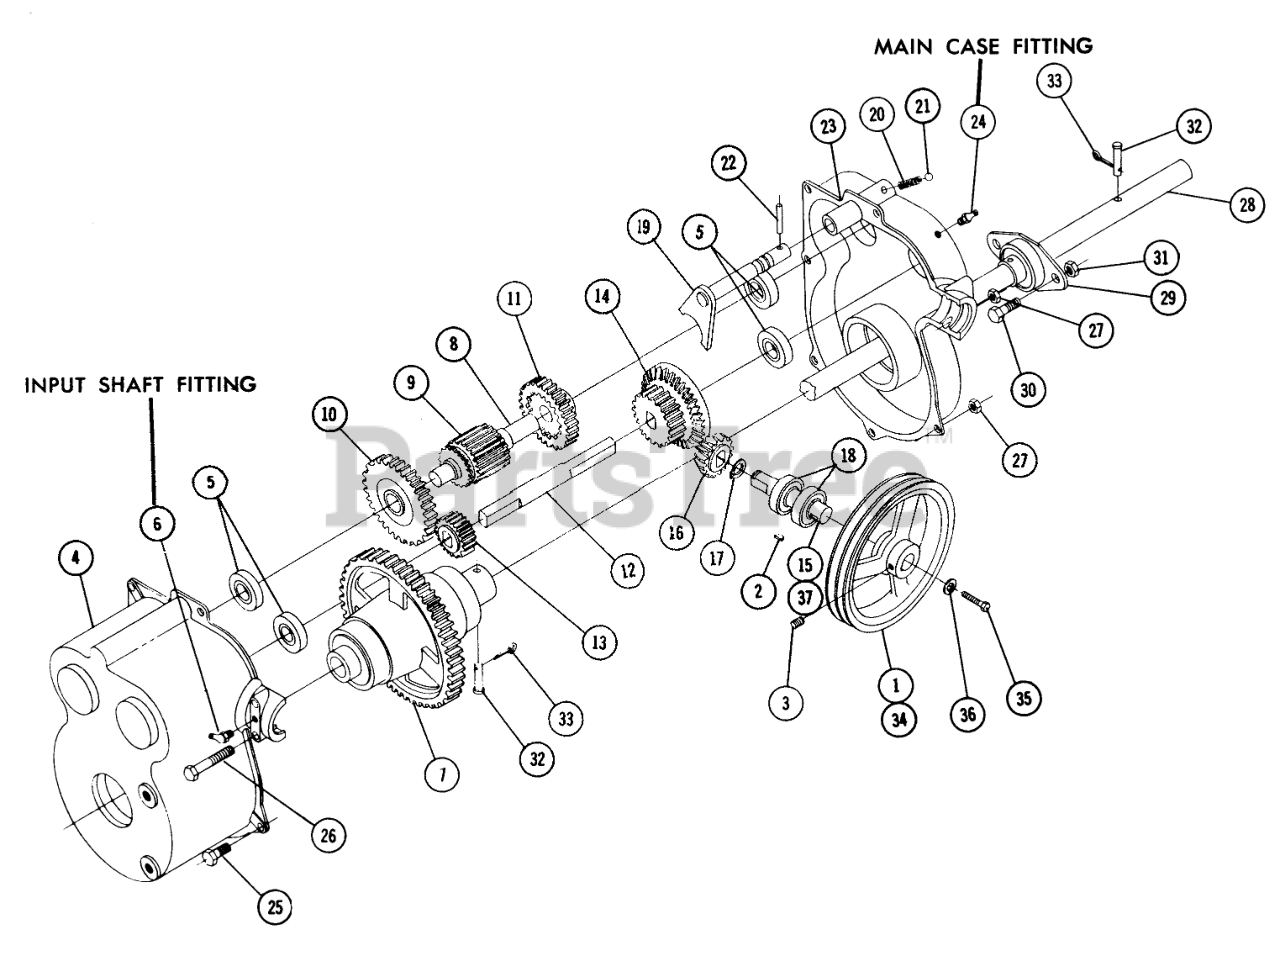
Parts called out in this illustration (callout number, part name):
1	Pulley
2	Key
3	Set Screw-Nylok
4	GEAR CASE
5	Ball Bearing 5/8 I.D.
6	ZERK 90DEGREE
7	Gear-Final Drive
8	Shaft-Sliding Gear
9	Gear-Sliding
10	Gear-Low
11	Gear-High
12	Shaft Hi-Low
13	Pinion Low
14	GEAR
15	Shaft-Input
16	PINION GEAR
17	SNAP RING- 5/8 EXT
18	Ball Bearing 5/8 I.D.
19	ASSY SHIFT FORK
20	Spring
21	BALL-DETENT
22	PIN-SPIROL
23	GEAR CASE
24	ZERK 90DEGREE
25	Bolt, 5/16-18 X 7/8
26	Bolt Hex 5/6-18 X 2-1/2
27	Nut-Nylok
28	AXLE
29	Bearing-Flanged Ball
30	Bolt Hex 3/8-16 x 5/8
32	Clevis Pin 1/4 x 1 1/2
33	Cotter Pin
